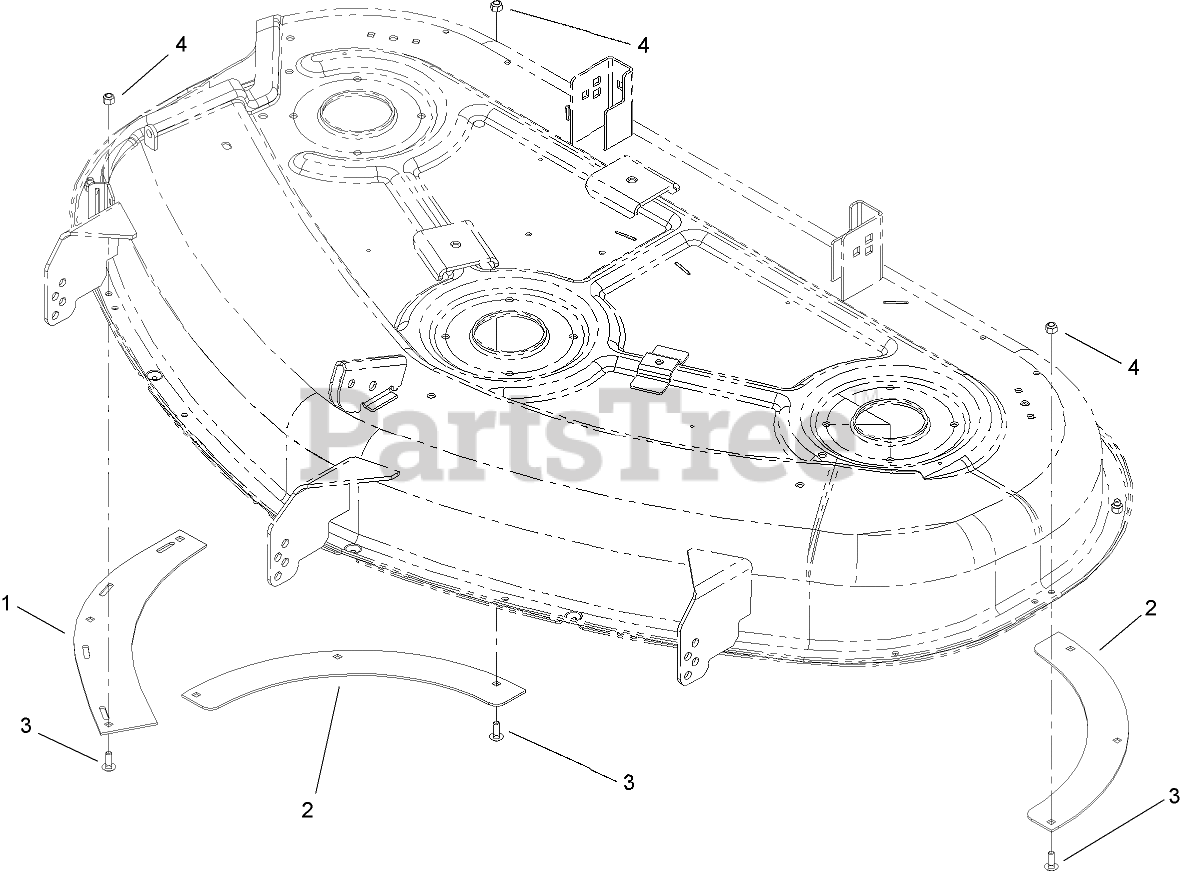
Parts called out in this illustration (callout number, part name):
1	BAFFLE-END
2	BAFFLE-REAR
3	BOLT-CARR
4	NUT-LOCK, NI
